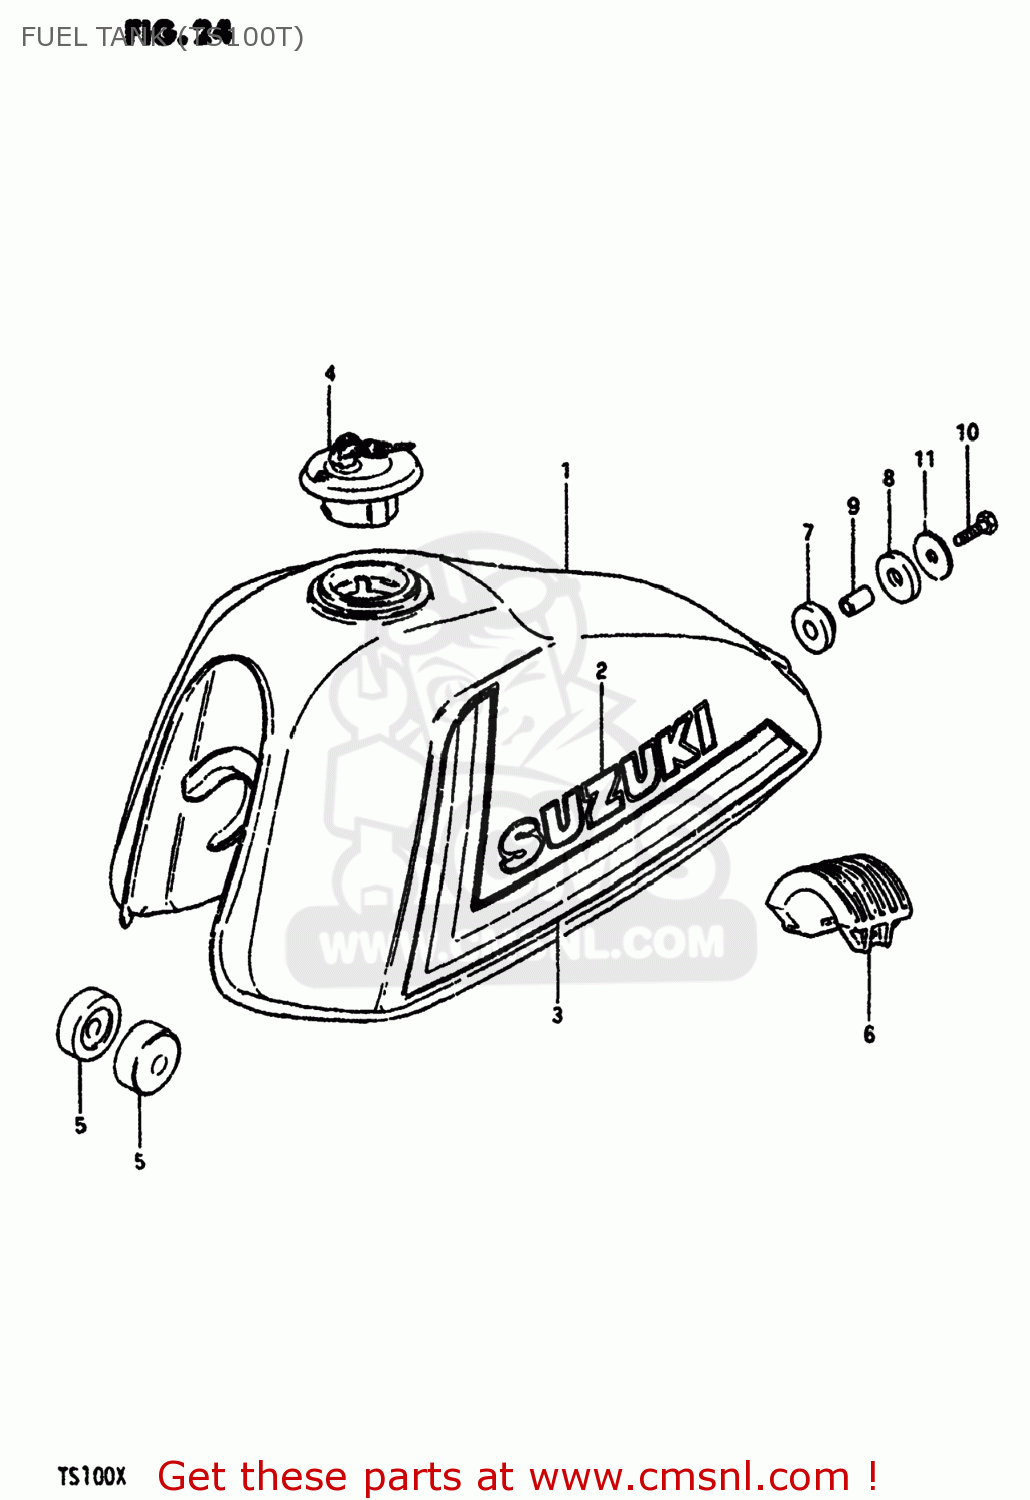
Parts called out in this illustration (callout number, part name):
1	TANK ASSEMBLY,FUEL
2	EMBLEM
3	TAPE SET,FUEL TANK
4	CAP SET,FUEL TANK
5	CUSHION
6	CUSHION,FUEL TANK
7	CUSHION
8	CUSHION
9	SPACER(8.5X12X19)
10	BOLT (8X30)
11	WASHER (8.5X29X1.6)
